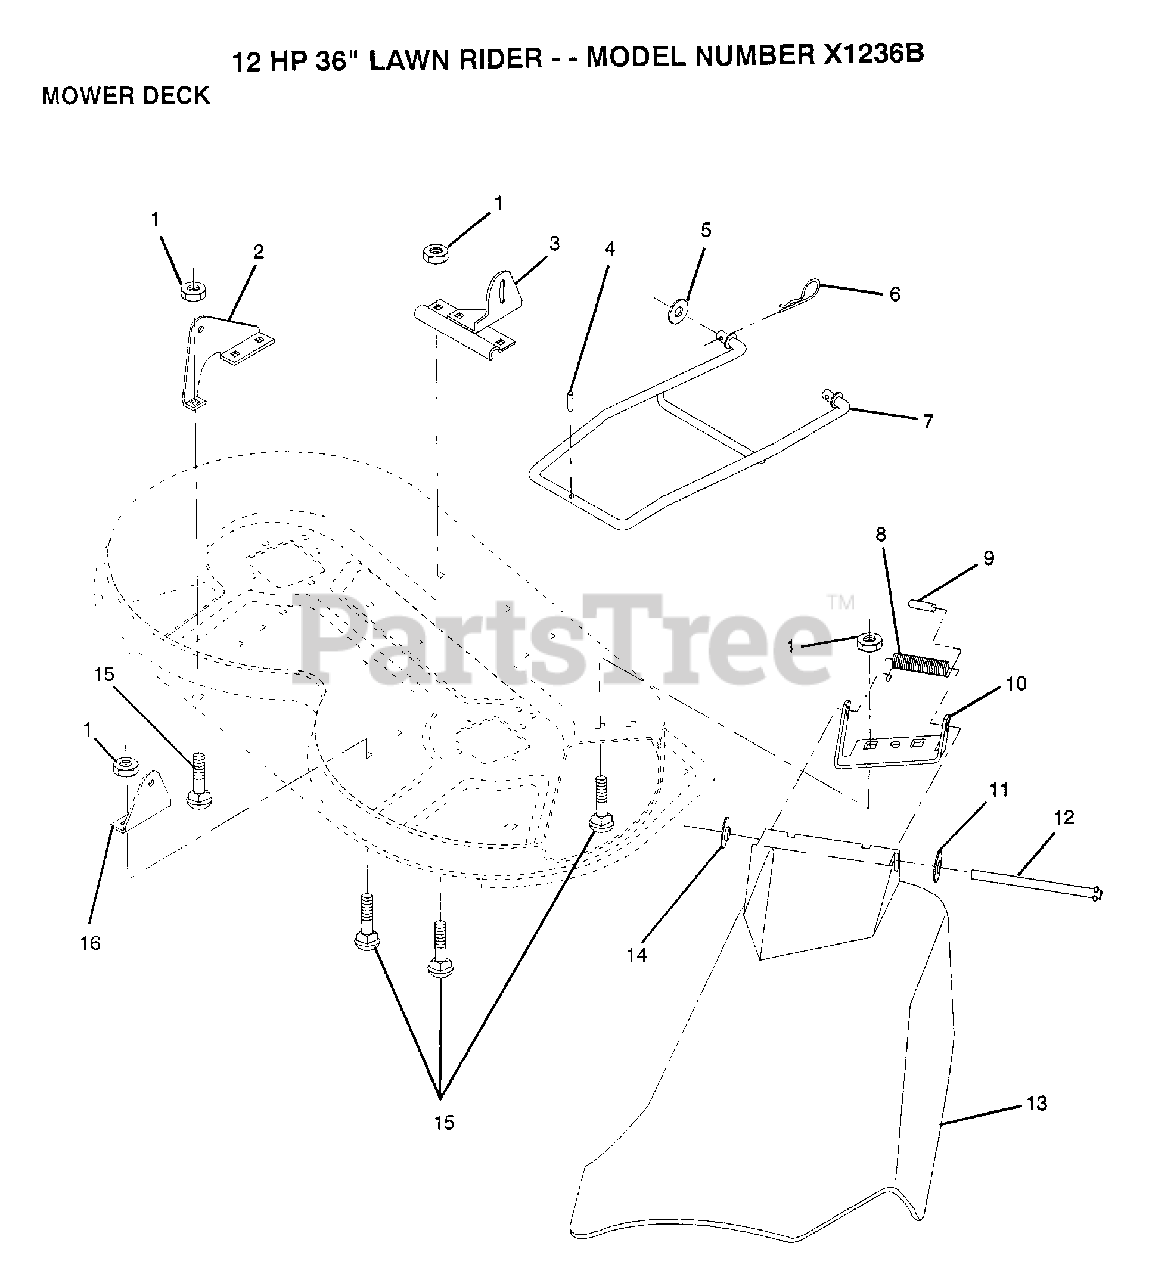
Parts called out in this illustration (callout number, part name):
2	"BRKT,LIFT REAR LH"
3	"BRKT,LINK STABILI"
4	"PIN,GROOVE"
6	RETAINER.SPRING
7	MOWER LINK STAB
8	SPRING TORSION
9	CAP-SLEEVE LT
11	WASHER
12	HINGE ROD
14	NUT PUSH M
15	BOLT
16	"BRKT,LIFT REAR"
